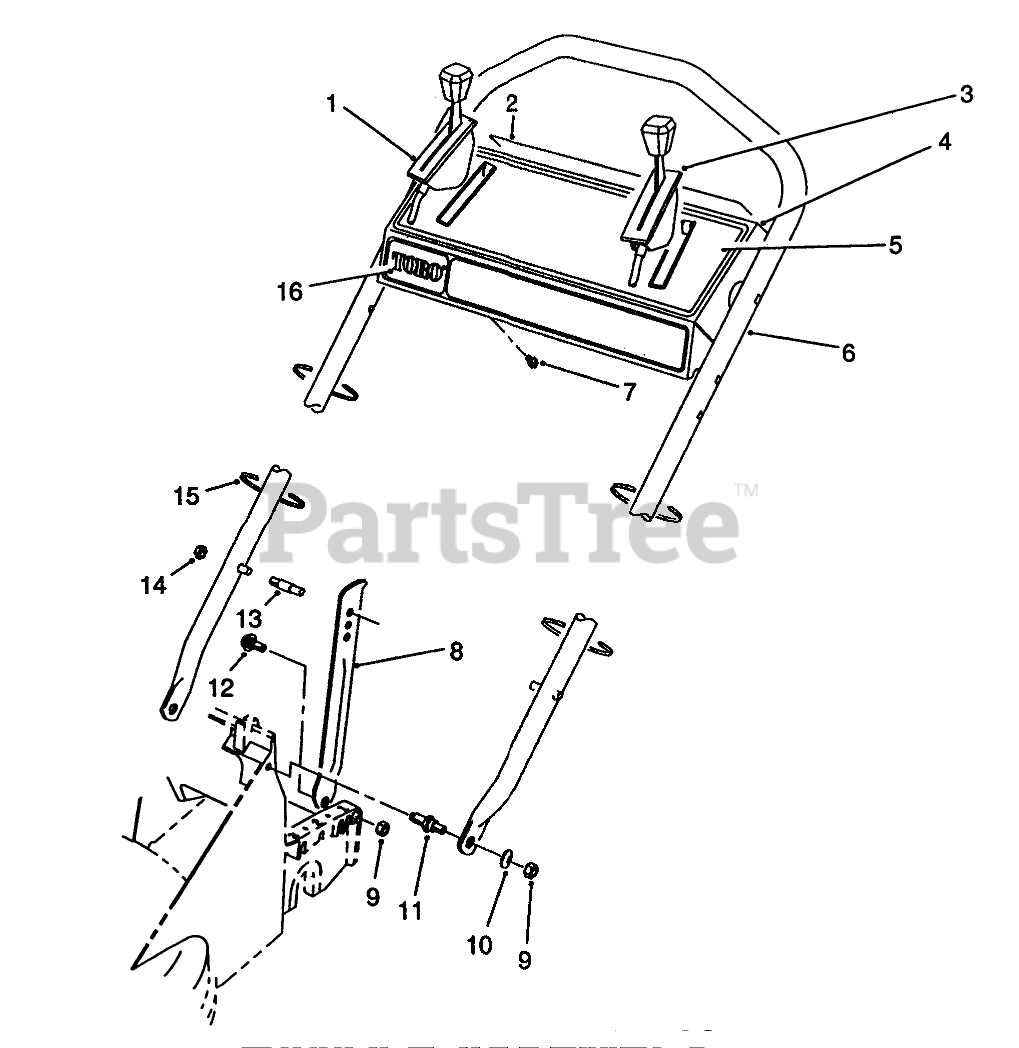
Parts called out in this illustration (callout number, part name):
1	Control-Ground Speed Bend Type #3 Sheath Lg. 51-1/4" Wire Lg. 2-1/8"
2	DECAL-PANEL, DANGER
3	Control-Throttle Bend Type #1 Sheath Lg. 54-1/2" Wire Lg. 2-3/16"
4	Control Panel Assembly (Incl. Ref. #2 & 5)
5	DECAL - INSTRUCTION
6	HANDLE
7	SCREW-HWHTF
8	HANDLE LATCH
9	NUT-LOCK, NI
10	WASHER-PLAIN
11	SCREW - SHOULDER STUD
12	SCREW - SHOULDER
13	HANDLE PIN
14	NUT-LOCK, NI
15	TIE-CABLE
16	DECAL - TORO PANEL
